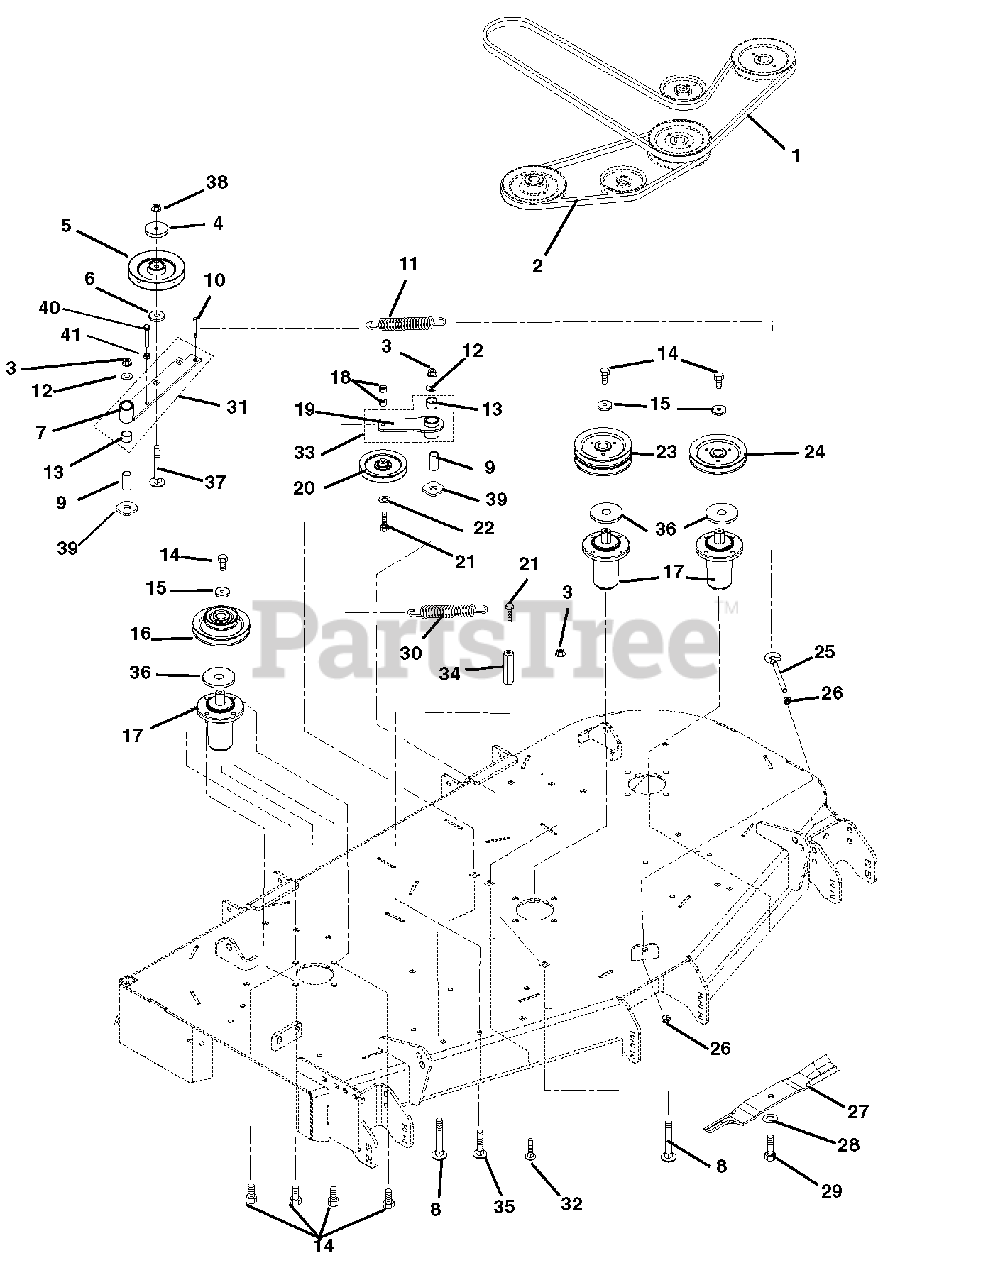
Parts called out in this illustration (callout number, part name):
1	Belt, 120.50" Long, PTO Drive Hex (191)
1	Belt, 130" Long, PTO Drive Hex (188, 189, 190)
1	Belt, 137" Long, PTO Drive Hex (192)
1	Belt, 147" Long, PTO Drive Hex (193)
2	V-Belt, 56" Long Cog B-Section (191)
2	V-Belt, 63" Long Cog B-Section (188, 189, 190)
2	V-Belt, 68" Long Cog B-Section (192)
2	V-Belt, 76" Long Cog B-Section (193)
3	Nut, .50-13 Nyloc Flange
4	Cap, Idler Bearing Sealing
5	Sheave, .50"ID x 6.00"OD V-Idler
6	Bushing, Spacer .502 x .997 x .50
7	Weldment, Idler Arm
8	Bolt, Round Head Square Neck .50-13 x 3.50
9	Bushing, Spacer .502 x .997 x 2.03
10	Bolt, Shoulder .38-16 x .30 Hex
11	Spring, Extension
12	Washer, Flat Steel .563 x 1.38 x .109
13	Bushing, 1.00 x 1.125 x 1.936
14	Bolt, Hex .38-16 x 1.00
15	Washer, Flat Steel .406 x 1.50 x .245
16	Sheave, Double, 1" ID x 6" OD and 3.50" OD (191)
16	Sheave, Double, 1" ID x 6.75" x 4.25" OD (188, 189, 190)
16	Sheave, Double 1"ID x 7.25" and 4.75"OD (192)
16	Sheave, Double, 1" ID x 8.25" and 5.25" OD (193)
17	Spindle Assembly (192, 193)
17	Spindle Assembly (188, 189, 190, 191)
18	Nut, Locking-Center .38-16
19	Weldment, Idler Arm
20	Assembly, V-Idler 5.00 O.D.
21	Bolt, Hex .38-16 x 2.25
22	Washer, Flat Steel .406 x .812 x .065
23	Sheave, Double 1" ID x 6.00" OD (191)
23	Sheave, Double 1" ID x 6.75" OD (188, 189, 190)
23	Weldment, Sheave (Double) 7.25 (192)
23	Sheave, Double 1" ID x 8.25" OD (193)
24	Sheave, Single 1" ID x 6.00" OD (191)
24	Sheave, Single 1" ID x 6.75" OD (188, 189, 190)
24	Sheave, Single 1"ID x 7.25" OD (192)
24	Sheave, Single 1"ID x 8.25" OD (193)
25	Bolt, .38-16 x 5.50 .62 Diameter Eye
26	Nut, Hex, Jam .375-16
27	Blade, 18.00" Mower (HI-LIFT) (191)
28	Washer, Bellville .63 x 1.625 x.14
29	Bolt, Hex .62-18 x 1.75 Grade 8
30	Spring, Extension
31	Assembly, PTO Idler Pivot Arm (Includes item # 7 and item # 13)
32	Bolt, Round Head Square Neck .50-13 x 1.5, Full Thread, Grade 5
33	Assembly, Idler Pivot Arm (Includes item # 13 and item # 19 )
34	Nut, Coupling .375-16 x 1.75
35	Bolt, Round Head Square Neck .38-16 x 1.00
36	Retainer, Grease
37	Bolt, Round Head Square Neck .50-13 x 3.00 Grade 5
38	Nut, Locking Center .50-13
39	Washer, Flat .640 x 1.75 x .250
40	Bolt, Hex .38-16 x 2.75
41	Nut, Hex .38-16
